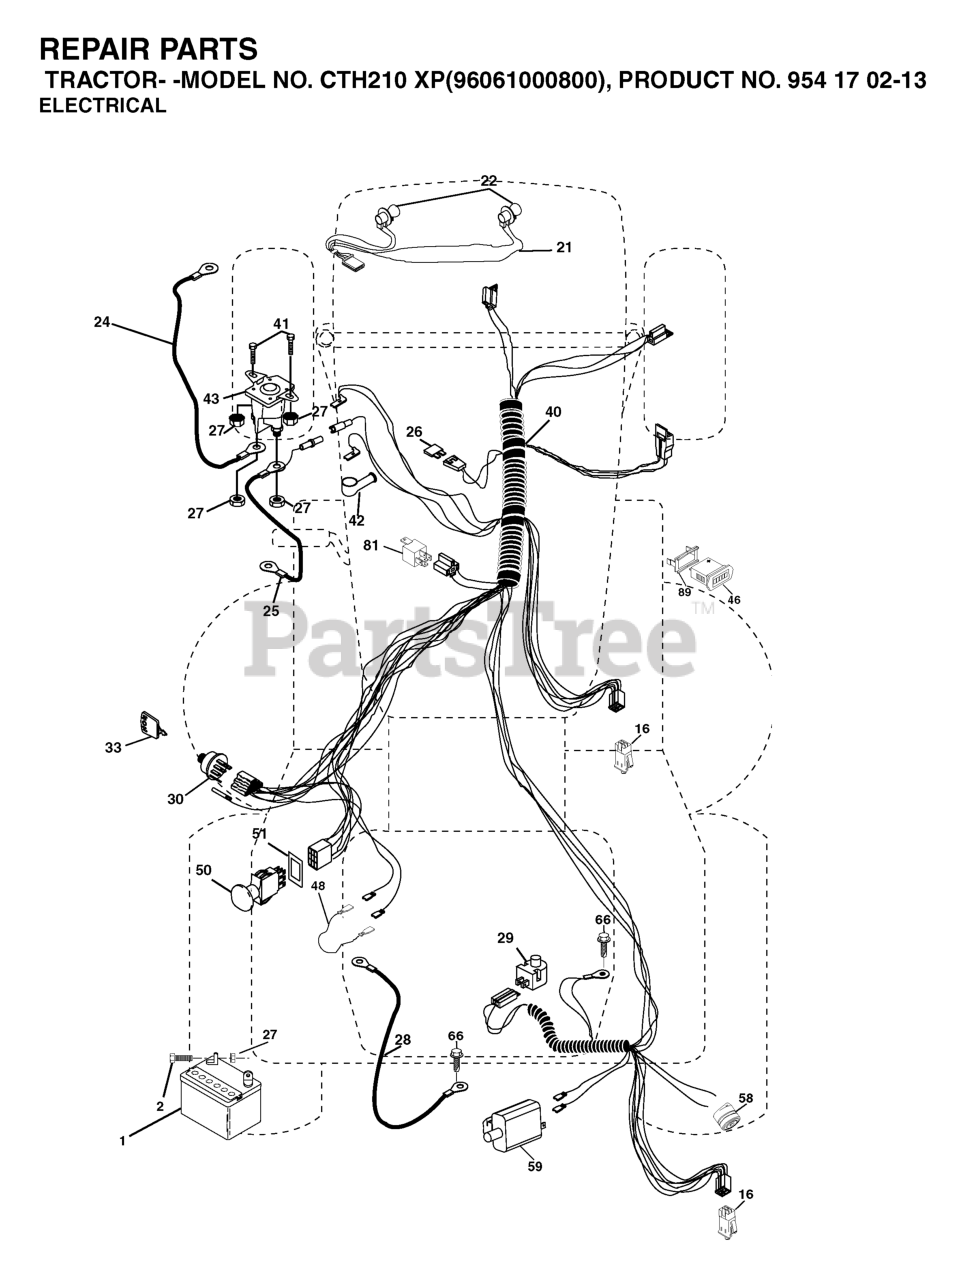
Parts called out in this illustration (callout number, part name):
1	BATTERY 12V .35 AMP
2	BOLT.HEX.1/4.X.3/4.DICHROMATE
16	SWITCH INTERLOOK PUSH-IN
21	HARNESS.W/LIGHT SOCKET
24	BATTERY CABLE
25	CABLE BATTERY
26	FUSE 20AMP
27	NUT
28	CABLE GROUND
29	RP.SWITCH.PLUNGER.NC.GRAY
30	IGNITION SWITCH
33	KEY MLD GEN DELTA
41	BOLT
42	TERMINAL COVER
43	SOLENOID
46	HOUR METER
48	ADAPTER.AMMETER
50	RP.PTO.SWITCH.8 TERMINAL.BLACK
51	FRAME RETAINING RING
58	BUZZER
59	.WITCH.FULL BAGGER.INDICATOR
81	RELAY.ASSY.T
89	BRACKET SNAP-IN HOURMETER
